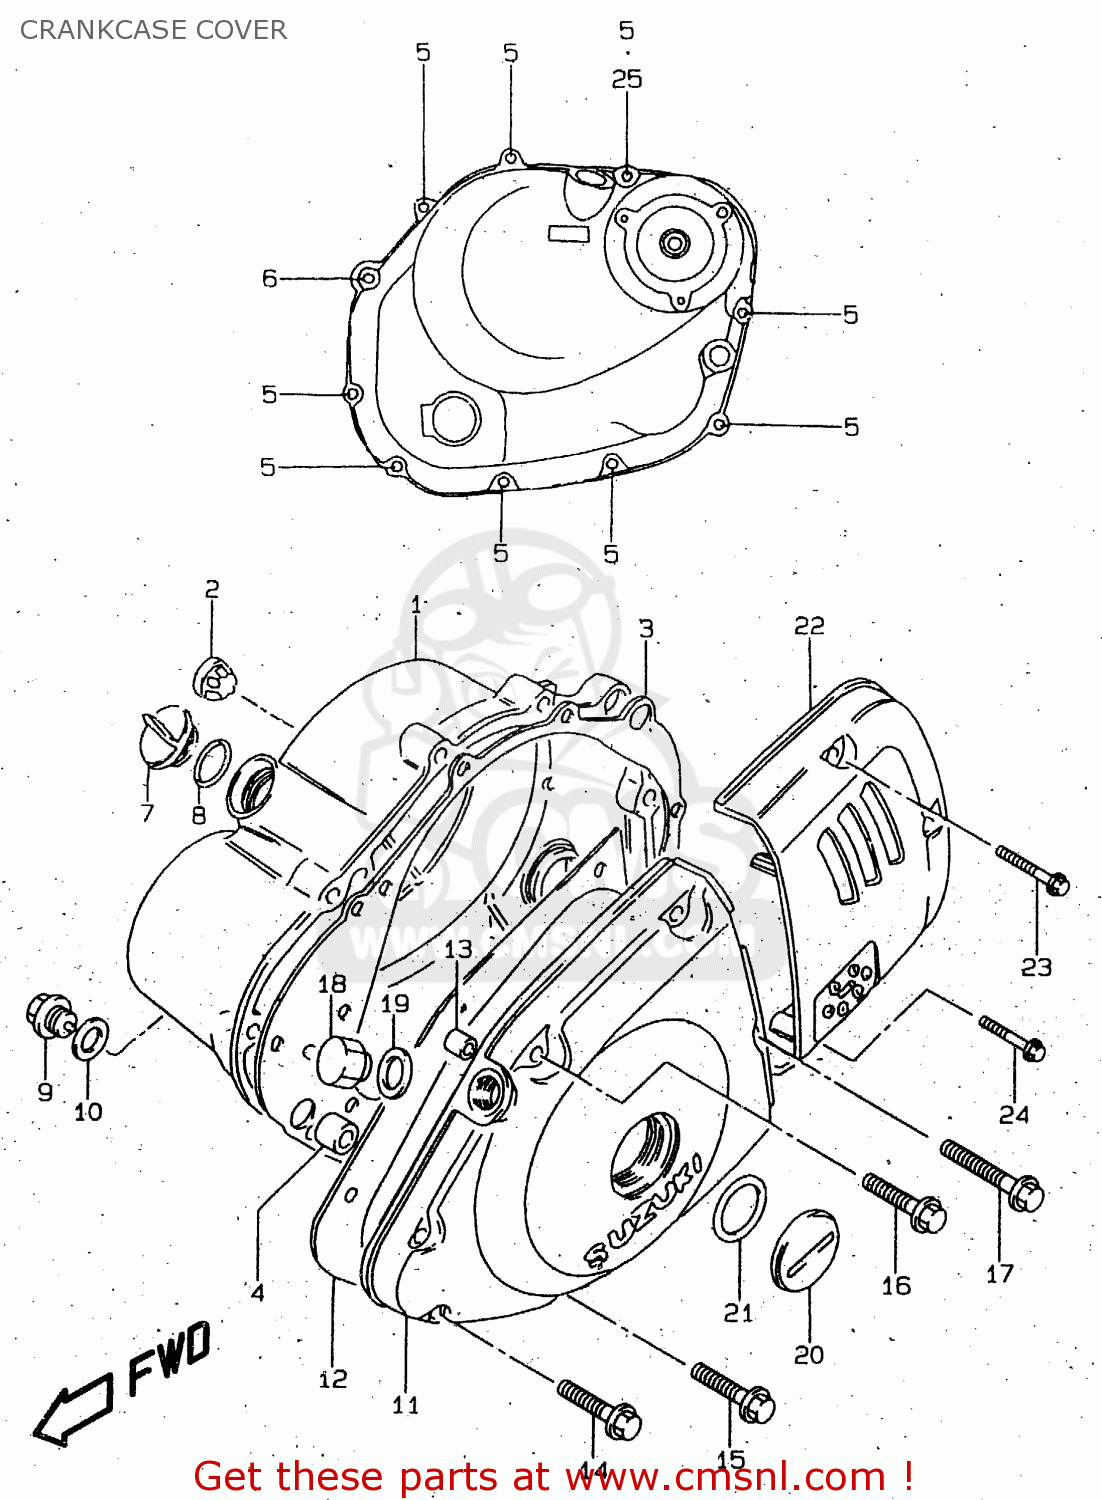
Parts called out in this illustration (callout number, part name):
1	COVER,CLUTCH
2	LENS,OIL LEVEL CHECK
3	GASKET,CLUTCH COVER (NAS)
4	PIN
5	BOLT
6	BOLT
7	PLUG(20X10)
8	O RING(D:3.1,ID:16.8)
9	PLUG(14X12)
10	GASKET(13.8X18.8X4.8) (NAS)
11	COVER,MAGNETO
12	GASKET,MAGNETO COVER (NAS)
13	PIN
14	BOLT
15	BOLT
16	BOLT
17	BOLT
18	PLUG,12X9
19	GASKET(12.1X16.2X3.7) (NAS)
20	PLUG(26X9)
21	O RING(D:3.1,ID:22.7)
22	COVER,ENGINE SPROCKET
23	BOLT
24	BOLT
25	GASKET(5.8X11X1.2) (NAS)
